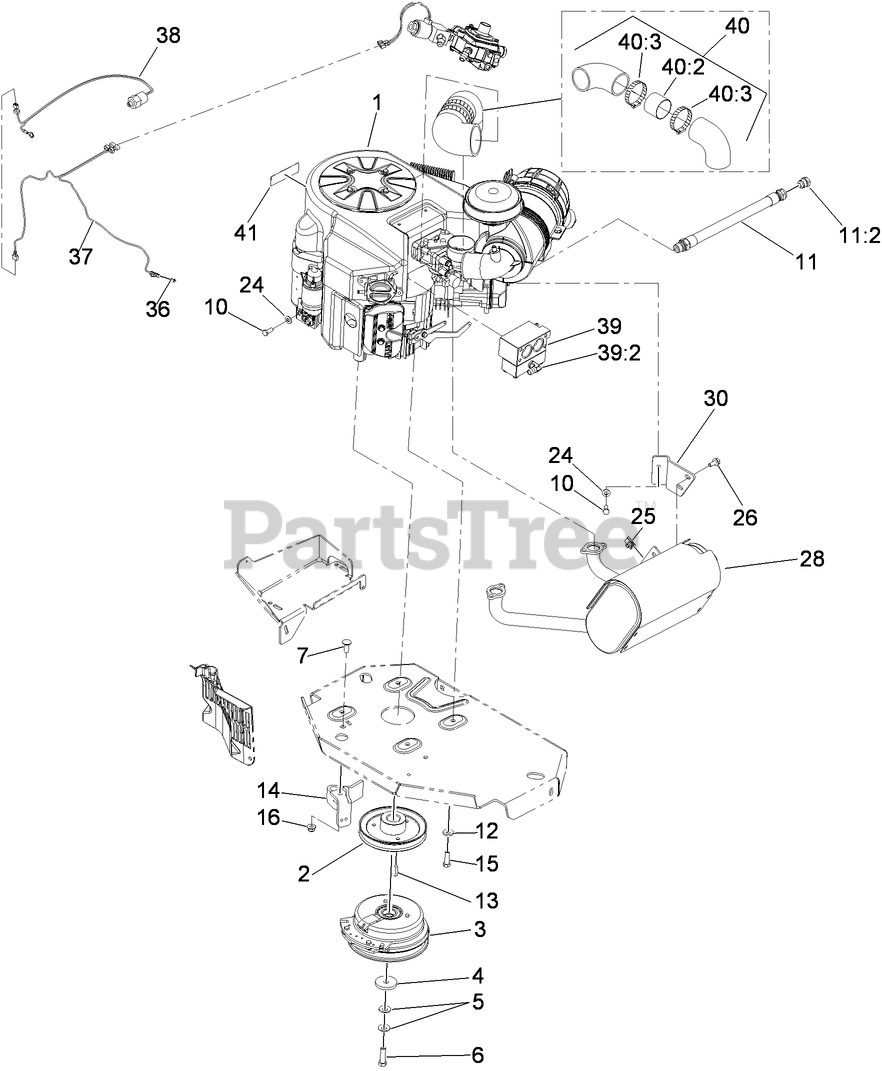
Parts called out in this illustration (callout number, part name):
2	SHEAVE
3	CLUTCH KIT
4	WASHER-CLUTCH
5	WASHER-SPRING
6	SCREW-HH, W/LOCTITE
7	SCREW-CARR
10	SCREW-HH
11	OIL DRAIN HOSE ASM
12	WASHER-BELLEVILLE
14	CLUTCH-ANCHOR
15	SCREW-HH
16	NUT-HF, NI
24	WASHER-SPRING
25	NUT-U
26	SCREW-HHF
28	MUFFLER
30	BRACKET-MUFFLER
36	TERMINAL-TAB
37	WIRE HARNESS
38	OIL PRESSURE SWITCH ASM
39	MIXER-LPG
39:2	ELBOW-90 DEG
40	AIR INTAKE HOSE ASM
40:2	SLEEVE-AIR INTAKE HOSE
40:3	CLAMP-HOSE
41	DECAL-LPG ENGINE
